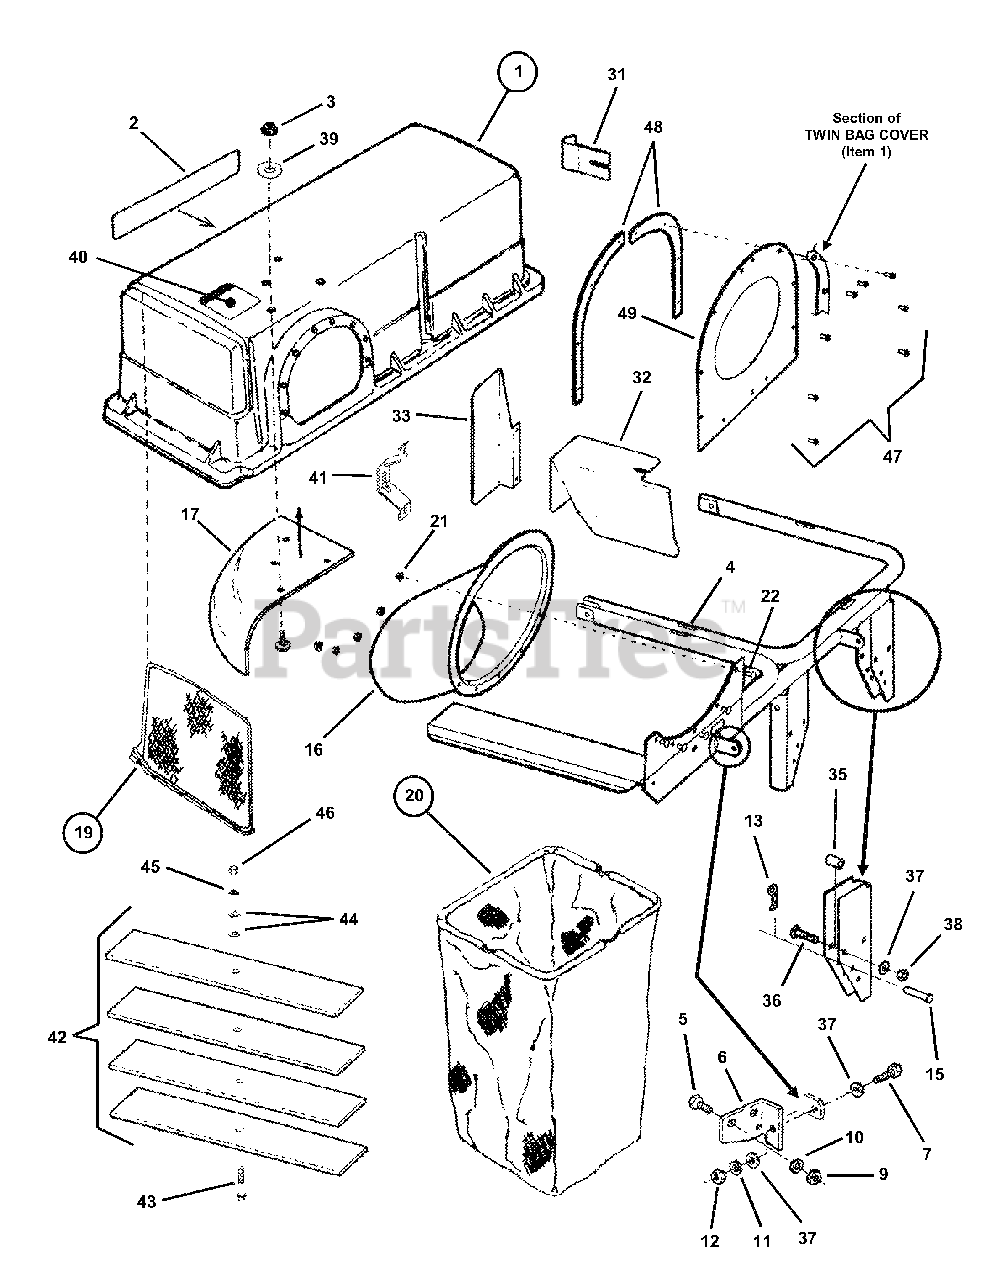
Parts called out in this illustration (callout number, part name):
1	ASS'Y, Cover
2	DECAL, Snapper
3	NUT, 1/4-20 Hex
4	WELDMENT, Frame
5	SCREW, 1/4-28 x 3/4"
6	HINGE, Top
7	SCREW, 5/16-24 x 1"
9	NUT, 1/4-28 Hex
10	WASHER, 1/4" Lock
11	WASHER, 5/16" Split
12	NUT, 5/16-24 Hex Center Lock
13	PIN, 3/32 x 1-1/2" Hair
15	PIN, 5/16 x 1-11/16" Clevis
16	INLET, Twin Bagger
17	SECTOR
19	ASS'Y, Screen (indented items)
20	ASS'Y, Bag (indented items)
21	NUT, 1/4-20 Hex Flange
22	BOLT, 1/4-20 x 1/2" Carriage
31	SUPPORT, Bumper
32	HEAT SHIELD
33	GUARD, Muffler
35	PAD, Bumper Mount
36	BOLT, 5/16-18 x 1-1/2" Carr.
37	WASHER, 5/16" Flat
38	NUT, 5/16-18 Hex Ctr. Lock
39	WASHER, 1/4" Flat
40	DECAL, Warning
41	BRACE, Twin Bag Catcher
42	BALLAST
43	SCREW, 3/8-16 x 2" Hex Cap
44	WASHER, 3/8" Flat
45	WASHER, 3/8" Split Lock
46	NUT, 3/8-16
47	SCREW, #10-24 x 1/2" Self-Tap
49	SEAL
